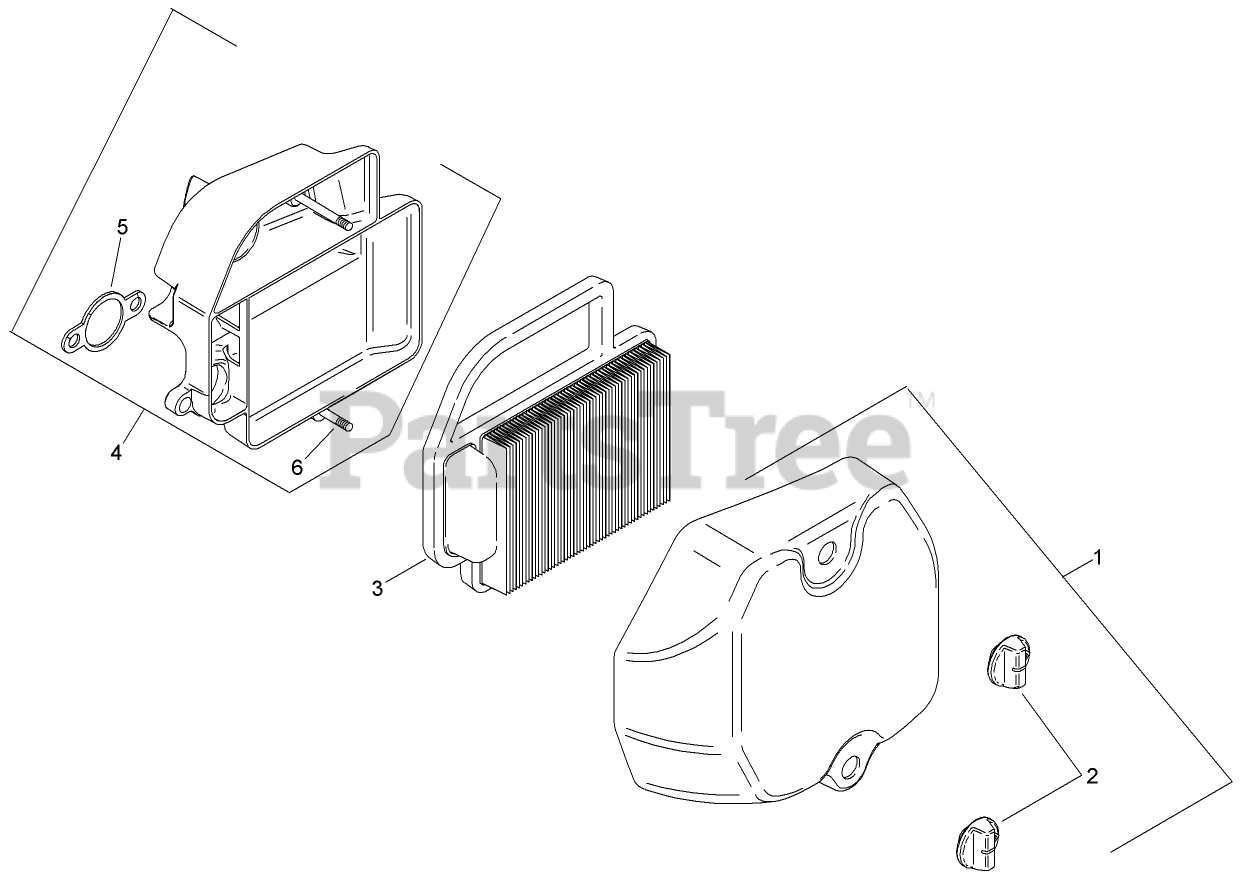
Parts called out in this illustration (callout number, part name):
1	AIR CLEANER COVER ASM
2	KNOB-COVER
3	Element-Cleaner, Air
4	AIR CLEANER BASE ASM (INCLUDES REF 1, 2)
5	Gasket-Base, Air Cleaner
6	STUD-BASE, AIR CLEANER
